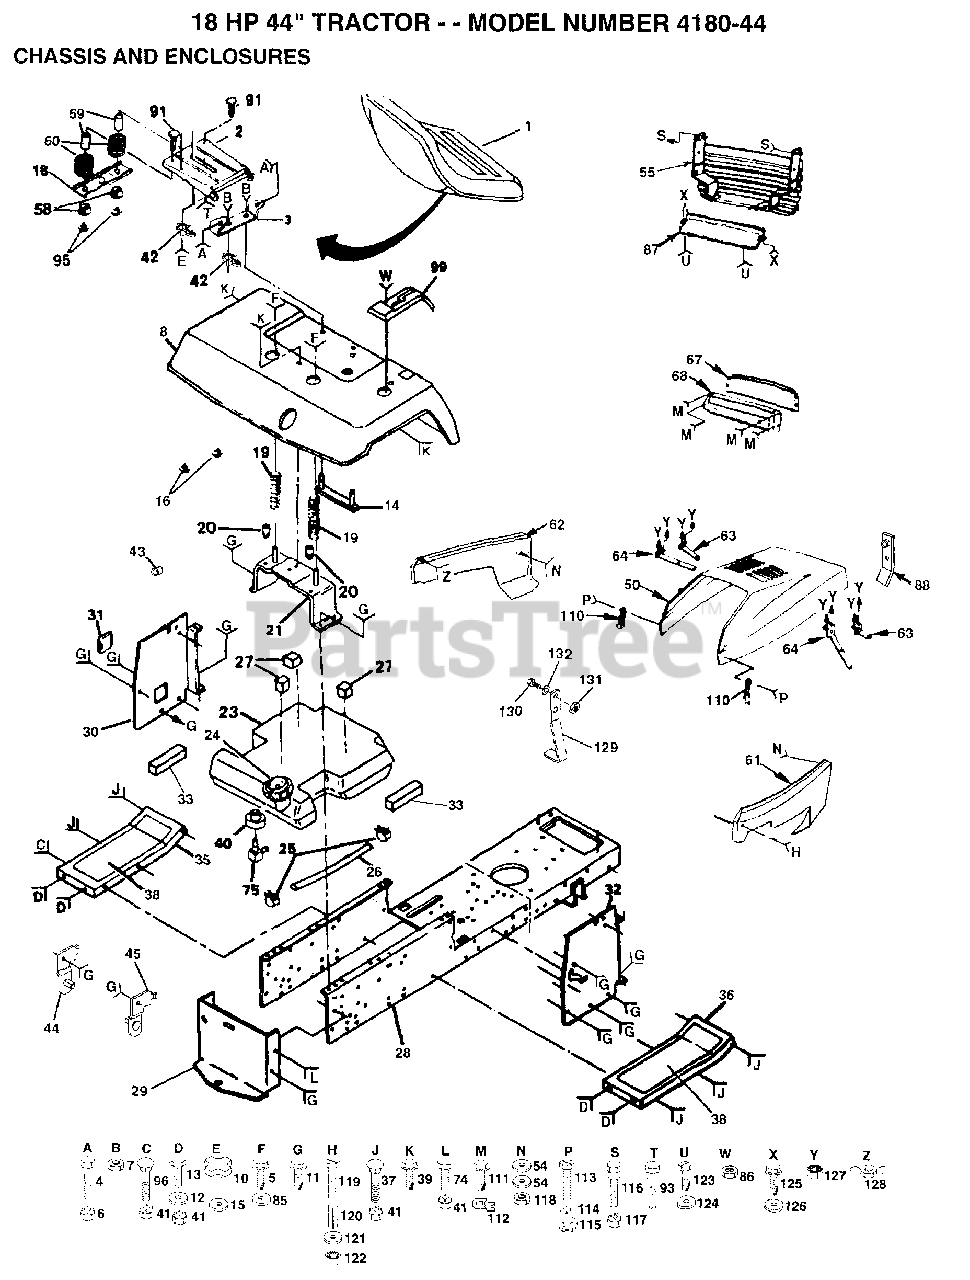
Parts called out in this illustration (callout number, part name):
3	BRACKET PVT SEAT
4	BOLT.SHLD.5/16-18
5	SCREW LT
10	"KNOB 1/2"" YT"
11	SCREW
12	WASHER
13	BOLT
14	STRAP ASM FENDER
15	WASHER
16	CAP SPRING
18	BRKT SWITCH
19	SPRING COMPRESSIO
20	NUT-PUSH YT
21	BRKT.ASM.FENDER
24	CAP ASM FUEL
25	HOSE CLAMP
26	FUEL LINE T
27	PAD-SPACER LT
29	DRAW BAR
30	PANEL.DASH.LH
31	COVER ACCESS
32	PANEL.DASH.RH
33	PAD IDLER TI
37	BOLT
38	FOOTREST PAD
39	SCREW LT
40	BUSHING OUTLET T
41	NUT
42	CLIP PUSH - IN
44	BRACKET ASM LH
45	BRACKET ASM RH
54	WASHER PM
58	BUSHING
59	SPACER SPLIT
60	SPRING COMPRESSED
62	PANEL SIDE LH
67	LENS LT
75	STEM.TANK.FUEL
85	WASHER
86	NUT
93	"BOLT,SHOULDER"
99	CONSOLE SHIFTER
110	HOOD LATCH T
112	"""J"" FASTENER LT"
113	SCREW
114	LOCKWASHER
115	WELDNUT
119	SCREW
120	SPACER LT
121	WASHER
123	SCREW
124	WASHER
125	SCREW HEX CRT
126	WASHER
127	NUT
129	STOP.OVER.CENTER
130	BOLT
131	NUT
132	WASHER GT
